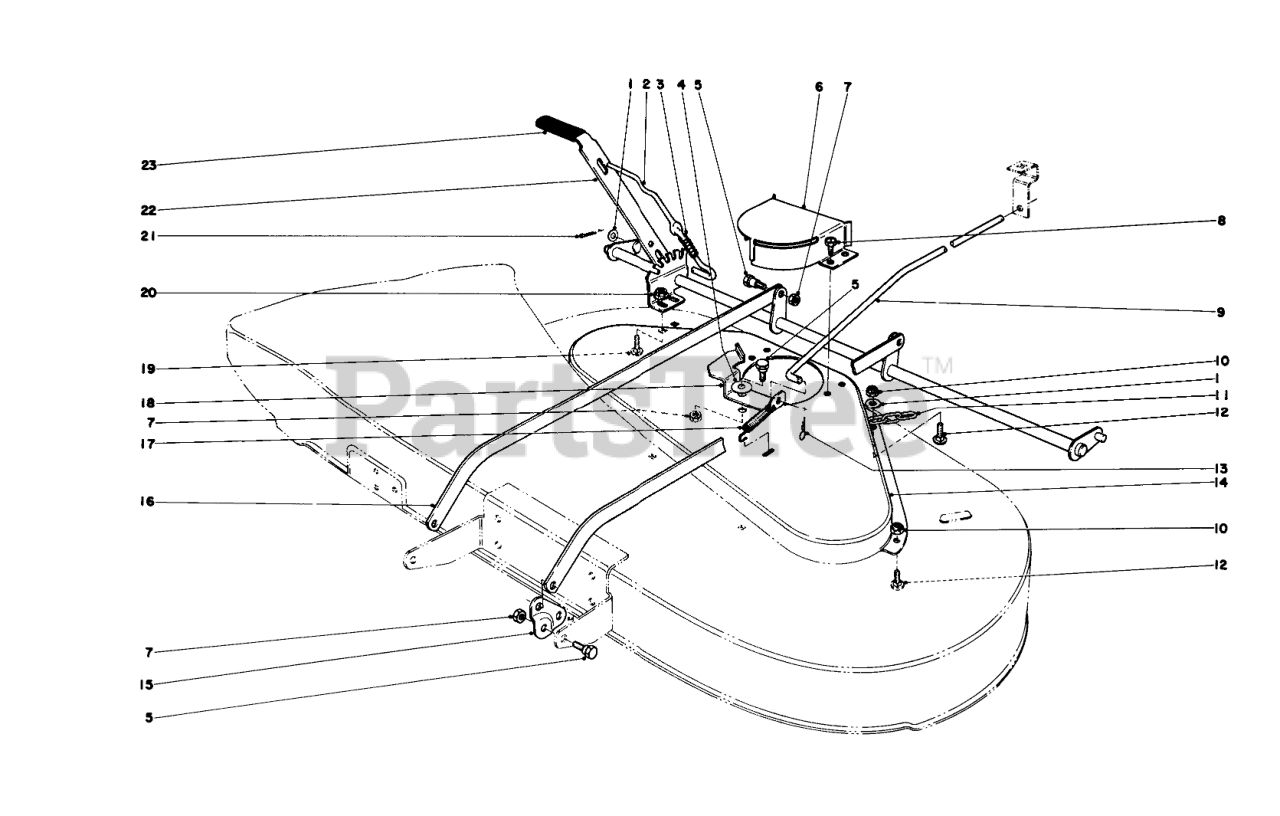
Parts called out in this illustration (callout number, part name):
1	WASHER-FLAT
2	Latch Slide
3	Spring
4	Washer Thrust
5	Screw
6	Cover Pulley
7	NUT-LOCK, CONE
8	SCREW-HWH
9	Rod-Blade Brake
10	NUT-LOCK, CONE
11	Chain
12	SCREW-CARR
13	PIN-COTTER
14	Cover Pulley
15	Blade Housing Pivot
16	Parallel Bar
17	Spring Blade Brake
18	Lever Blade Brake
19	BOLT-CARR
20	NUT-HF
21	PIN-COTTER
22	Shaft Assembly
23	Grip Handle
